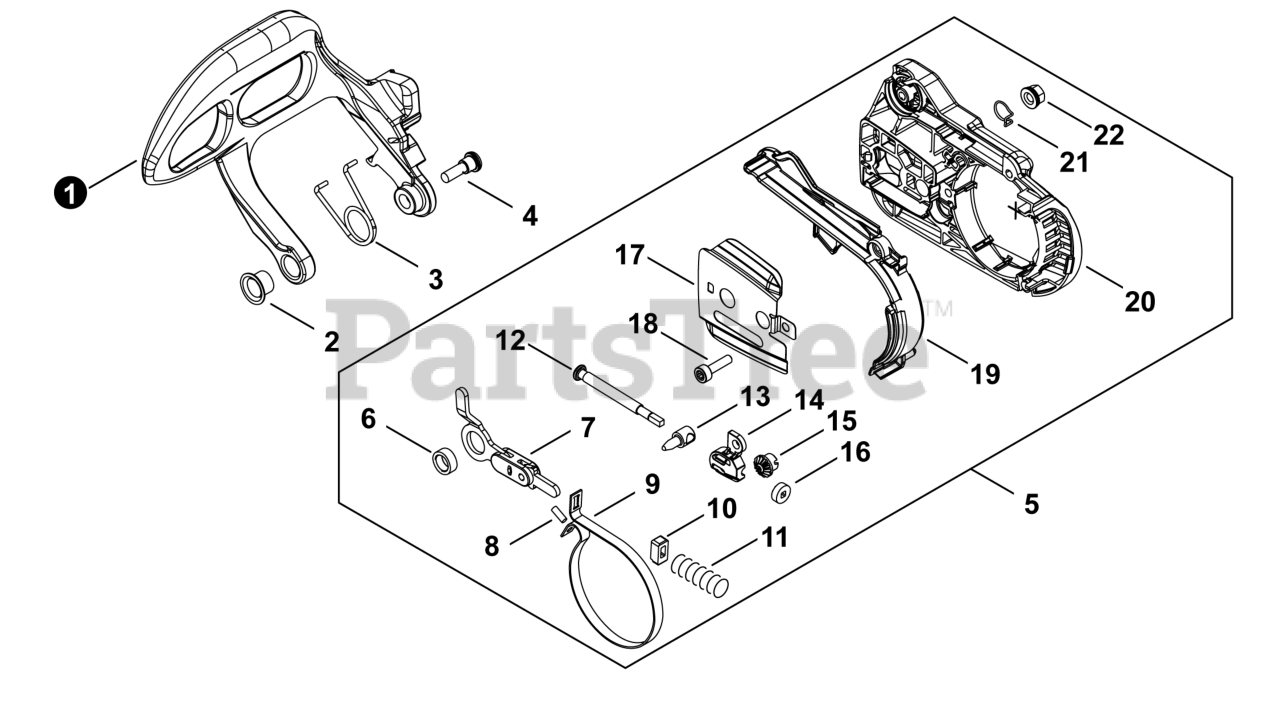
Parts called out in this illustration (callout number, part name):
1	LEVER, BRAKE
2	COLLAR 10
3	SPRING, TORSION
5	SPROCKET GUARD ASSY
6	COLLAR 8
7	CONNECTOR, BRAKE
9	BAND, BRAKE
11	SPRING, COMPRESSION
13	TENSIONER, CHAIN
14	COLLAR 8
15	GEAR, BEVEL
16	GEAR, BEVEL
17	PLATE, GUIDE - OUTER
18	BOLT, TORX 4×12
19	COVER, BRAKE
20	GUARD, SPROCKET
